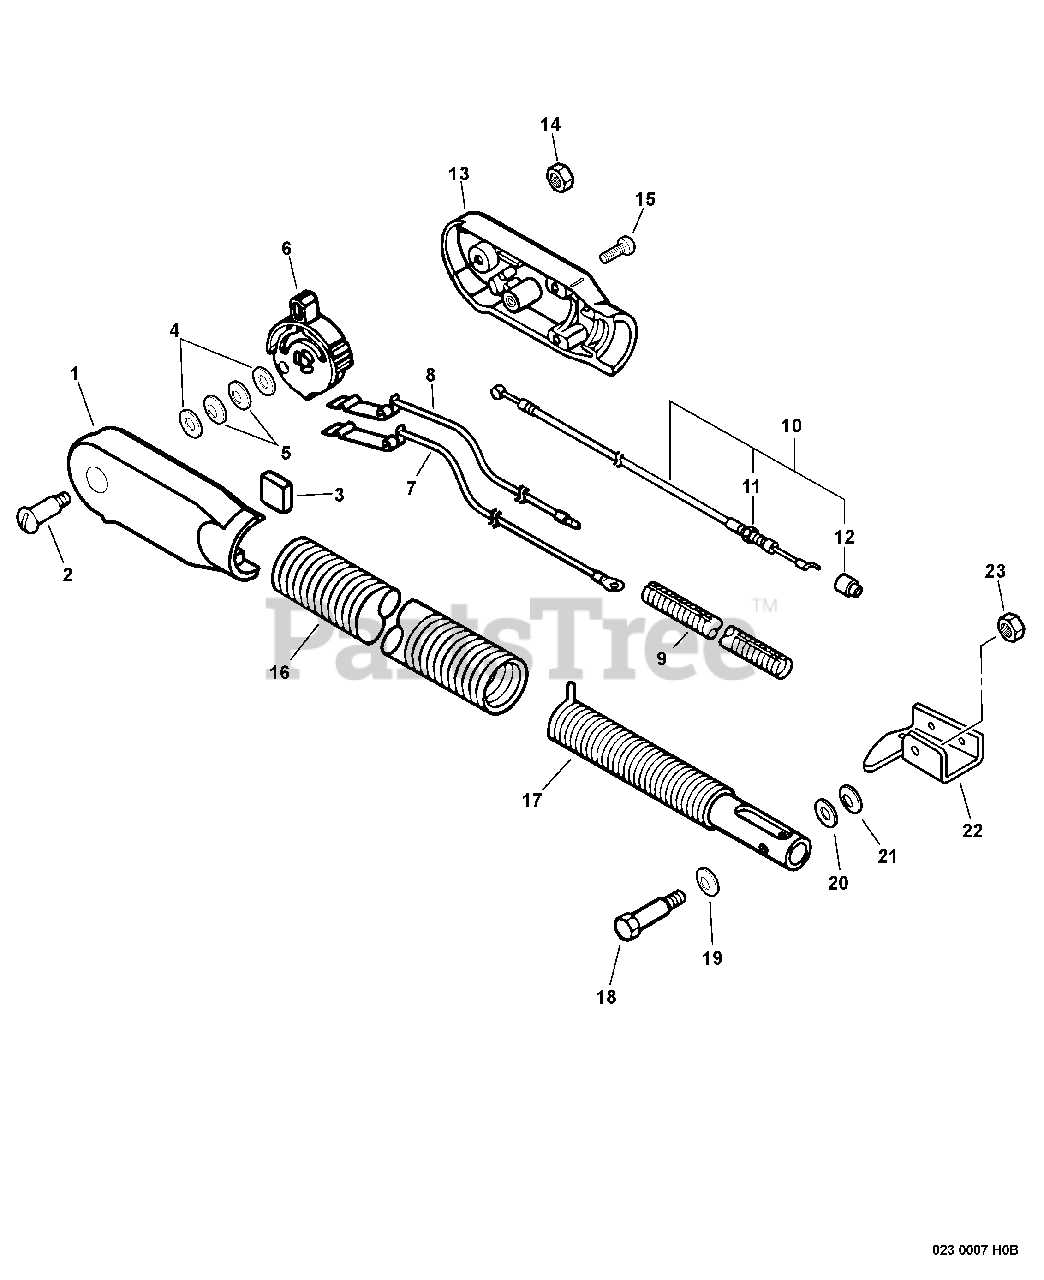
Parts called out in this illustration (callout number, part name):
1	HANDLE, CONTROL - LEFT
2	SCREW - 4
3	PAD, FOAM
4	WASHER - 6
5	WASHER - SPRING
6	LEVER, THROTTLE CONTROL
7	LEAD - GROUND
8	LEAD, SPRING SWITCH
9	TUBE, PROTECTIVE - CORRUGATED
10	THROTTLE CABLE ASSY
11	LOCKNUT - 6
12	CAP, DUST
13	HANDLE, CONTROL - RIGHT
14	LOCKNUT - 4
15	SCREW - 5X20
16	TUBE, OUTER
17	SPRING TUBE ASSY
18	BOLT - 6
19	WASHER - SPRING
20	WASHER - 8
21	WASHER - SPRING
23	LOCKNUT - 1/4"
